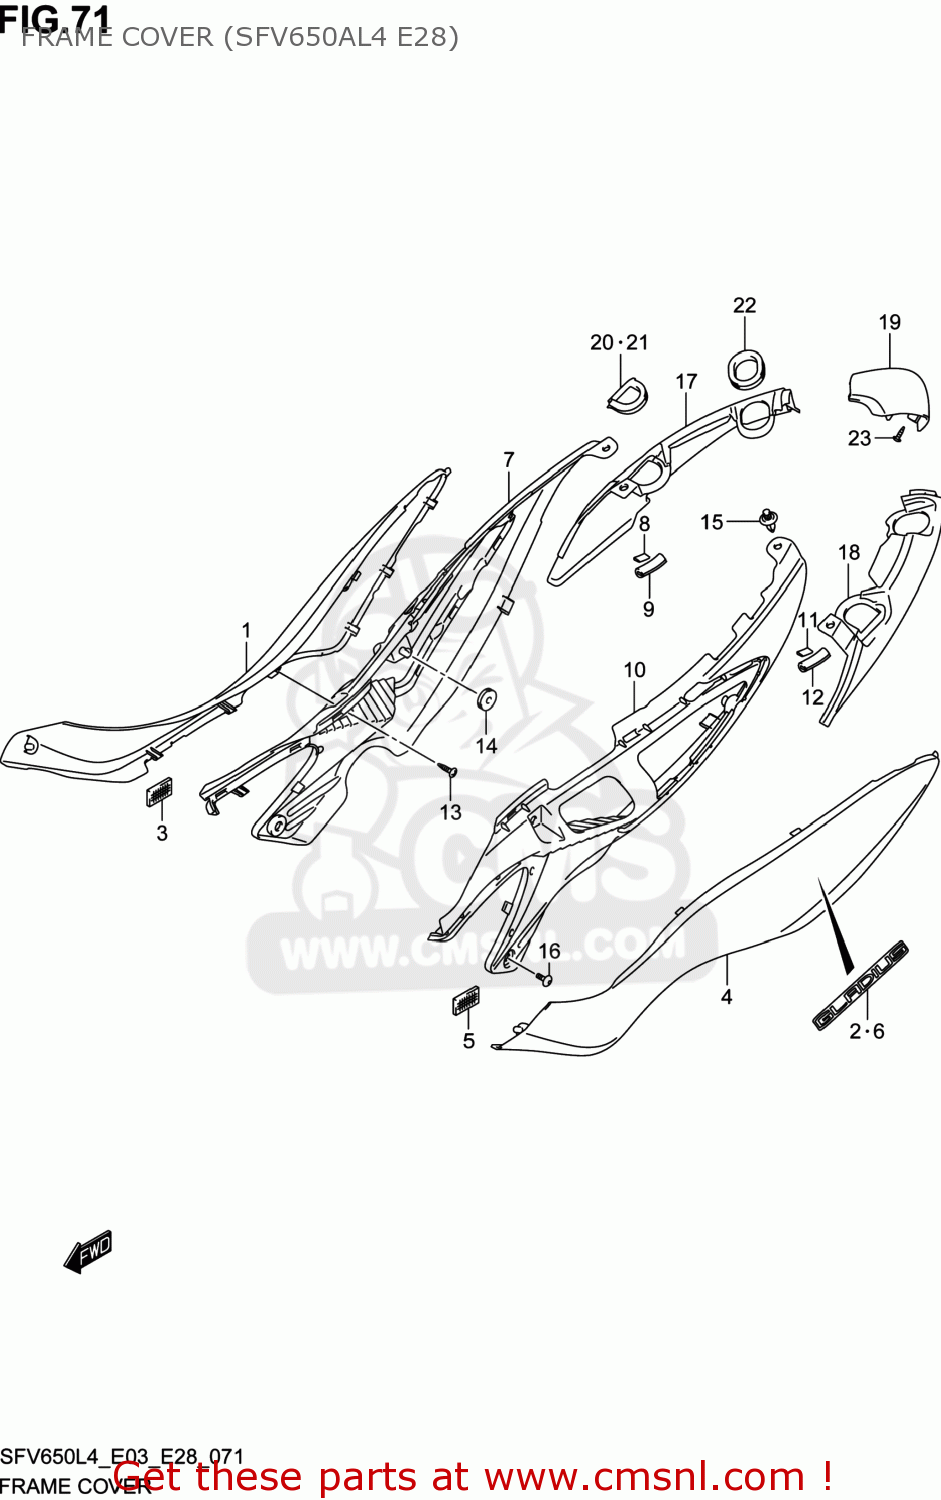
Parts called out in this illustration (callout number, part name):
1	COVER,FRAME,R(GRAY)
2	EMBLEM,FRAME COVER
3	FASTENER,FRAME COVER
4	COVER,FRAME,L
5	FASTENER,FRAME COVER
6	EMBLEM,FRAME COVER
7	COVER,FRAME RR,R
8	TAPE,DRAIN WASHER
9	MOLDING
10	COVER,FRAME RR,L
11	TAPE,DRAIN WASHER
12	MOLDING
13	SCREW
14	CUSHION
15	CLIP(BLACK)
16	SCREW(5X13)
17	COVER,FRAME RR CTR,R
18	COVER,FRAME RR CTR
19	COVER,FRAME RR CTR RR
20	CUSHION,COVER RR CTR,R
21	CUSHION,COVER RR CTR,L
22	CUSHION,COVER RR CTR RR
23	SCREW
